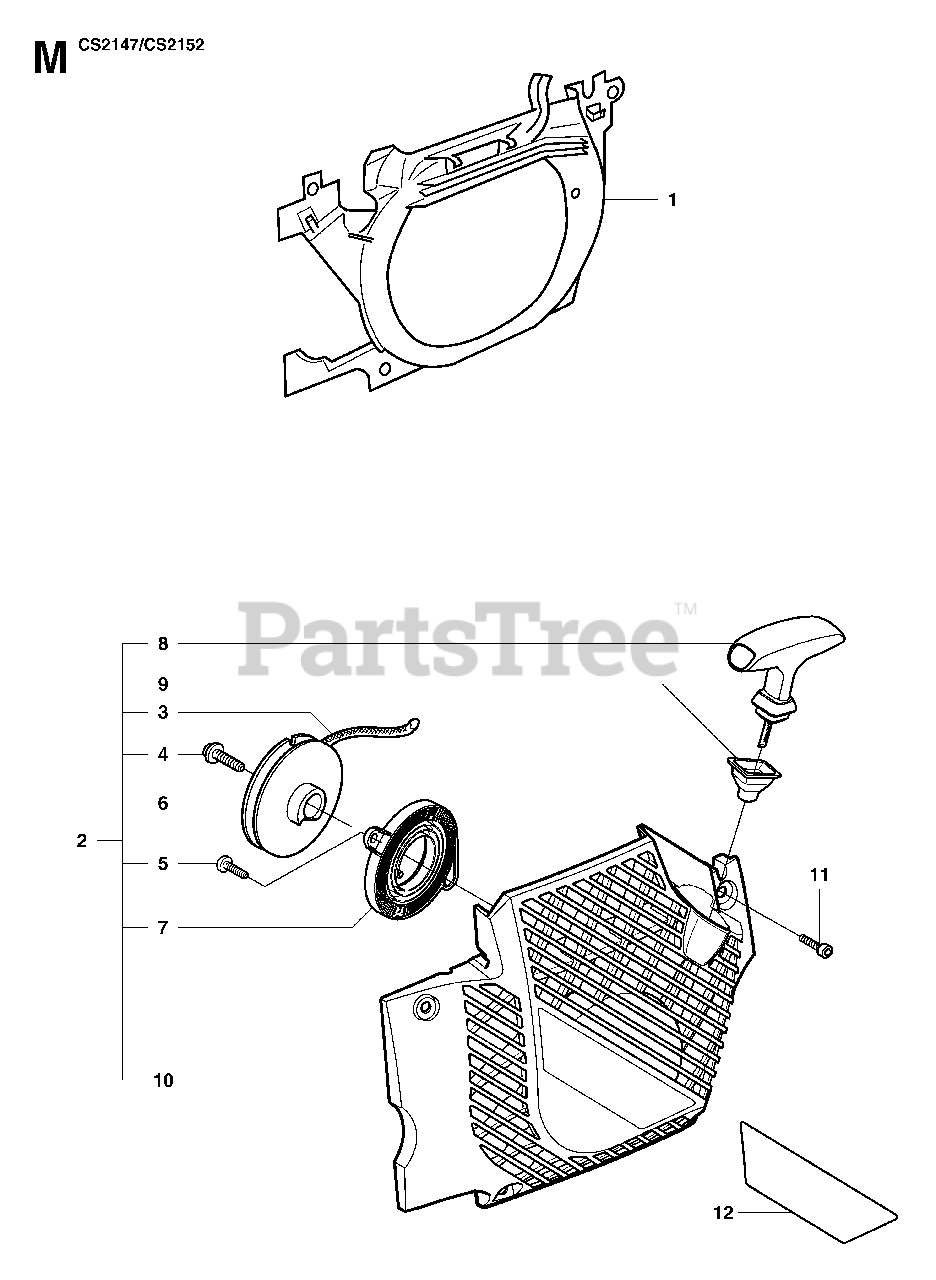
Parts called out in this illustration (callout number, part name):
1	AIR CONDUCTOR
2	STARTER ASSY.
3	STARTER ROPE
6	PULLEY
7	RETURN SPRING
8	STARTER HANDLE
10	STARTER HOUSING
12	DECAL (CS 2147 C)
12	DECAL (CS 2147 W)
